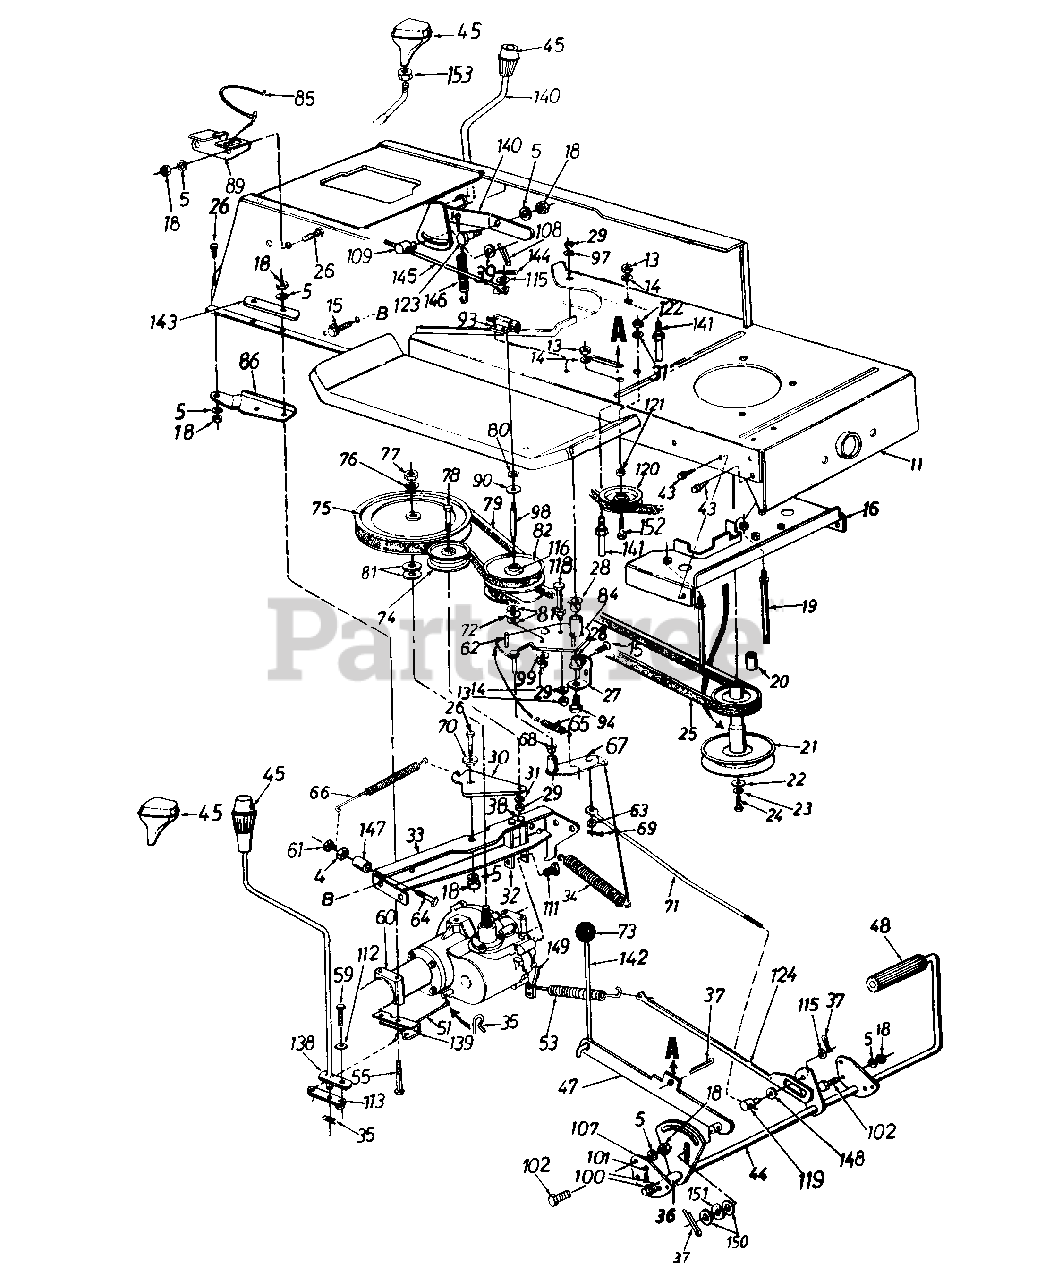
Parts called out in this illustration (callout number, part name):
4	Hex Nut 5/16-24 Thd.
5	L-Wash. 5/16" I.D.
14	L-Wash 1/4" I.D.
15	Hex Wash TT-Tap Scr. 5/16-18 x .62" Lg.
18	Hex Nut 5/16-18 Thd.
19	Belt Guard Stud 3.6" Lg.
20	Spacer 1" I.D.
21	Engine Pulley
22	Fl-Wash. 7/16" I.D. x 1.25"
23	L-Wash. 7/16" I.D.
24	Hex Bolt 7/16-20 x 1.50" Lg.
25	Variable-Speed Belt
26	Hex Bolt 5/16-18 x .75" Lg.
27	Bearing Shaft Bracket
28	Flanged Nyliner Brg. .63" I.D. x .6" Lg.
29	Hex Nut 3/8-24 Thd.
30	Idler Bracket
31	L-Wash. 3/8" I.D.
35	Inter. Cotter Pin
36	Spacer .63" I.D.
37	Cotter Pin 1/8" Dia. x 1.25" Lg.
38	Self-Tap Scr. 5/16-18 x .5" Lg.
39	Fl-Wash. .51" I.D. x .75"
43	Hex Wash. Hd. S-Tap Scr. 1/4-20 x .50" Lg.
44	Clutch/Brake Pedal Ass'y.
45	Shift Knob
47	Parking Brake Lockout Brkt. Ass'y.
48	Foot Pad
51	Shift Lever Rod
53	Ext. Spring 3.6"
55	Hex Bolt 5/16-18 x 3.25"
59	Hex Bolt 1/4-28 x .62" Lg.
60	Transaxle Complete
61	Hex L-Nut 1/4-20 Thd.
62	Belt Guard Pin 1/4-20 Thd.
63	Fl-Wash. .34" I.D. x .68" O.D.
64	Hex Wash. TT-Tap Scr. 1/4-20 x 1.75"
65	Ext. Spring 2.59" Lg.
66	Ext. Spring .5" O.D. x 4.35"
68	Flanged Bearing
69	Cotter Pin 3/32" Dia.
70	Shoulder Spacer .27" Lg.
71	Speed Control Link
72	Truss Bearing .56 Dia. x 1.25"
73	Ball Knob
74	Fl-Idler Pulley 3.25" x .75"
75	"V"-Pulley
76	L-Wash. 1/2" I.D.
77	Hex Jam Nut 1/2-20 Thd.
78	Hex Bolt 3/8-24 x 1.75: Lg.
79	Variable Speed Belt
80	Snap Ring .56" Dia.
81	Fl-Wash. .56" I.D. x 1.0" O.D.
82	Variable Speed Pulley Ass'y. 5" O.D.
90	Teflon Washer .565" I.D.
93	Safety Switch (Clutch)
94	Shld. Bolt 3/8-24 x 3.12" Lg.
97	Bell-Wash. .38" I.D. x .88"
98	Shaft
99	Bell-Wash. .39" I.D. x 1.12"
100	Fl-Wash. .64" I.D. x .94"
101	Cotter Pin 1/8" Dia. x 1.25"
102	Hex Wash. Hd. Scr. 5/16-18 x .62" Lg.
109	Ferrule
111	Hex Wash. Tap Scr.
112	Bell-Wash. .265" I.D. x .75"
113	Shift Lever Link Ass'y.
115	Fl-Wash. .385" I.D. x .62"
116	Needle Brgs.
118	Belt Keeper 3" Lg.
119	Ferrule
120	Fl-Idler w/Flanges 2.75" O.D.
121	Fl-Wash. .39" I.D. x 1.12" O.D.
122	Hex Nut 3/8-16 Thd.
123	Shld. Bolt .437" Dia. x .162"
124	Brake Rod Ass'y.
138	Shift Lever Ass'y.
139	Shift Lever Support Brkt.
140	Speed Selector Lever Ass'y.
141	Belt Guard Pin
142	Brake Lockout Rod
144	Cotter Pin 1/8" x 3/4" Lg.
145	Speed Selector Rod
146	Ext. Spring 3.97" Lg.
147	Spacer .326" I.D. x .47"
148	Fl-Wash. 5/8" I.D. x 1.25"
149	Actuating Arm
150	Fl-Wash. .385" I.D. x .87" O.D.
151	Wave Wash. .38" I.D. x .75"
152	Hex Bolt 3/8-16 x 1.25" Lg.
153	Hex Jam Nut 3/8-16 Thd.
